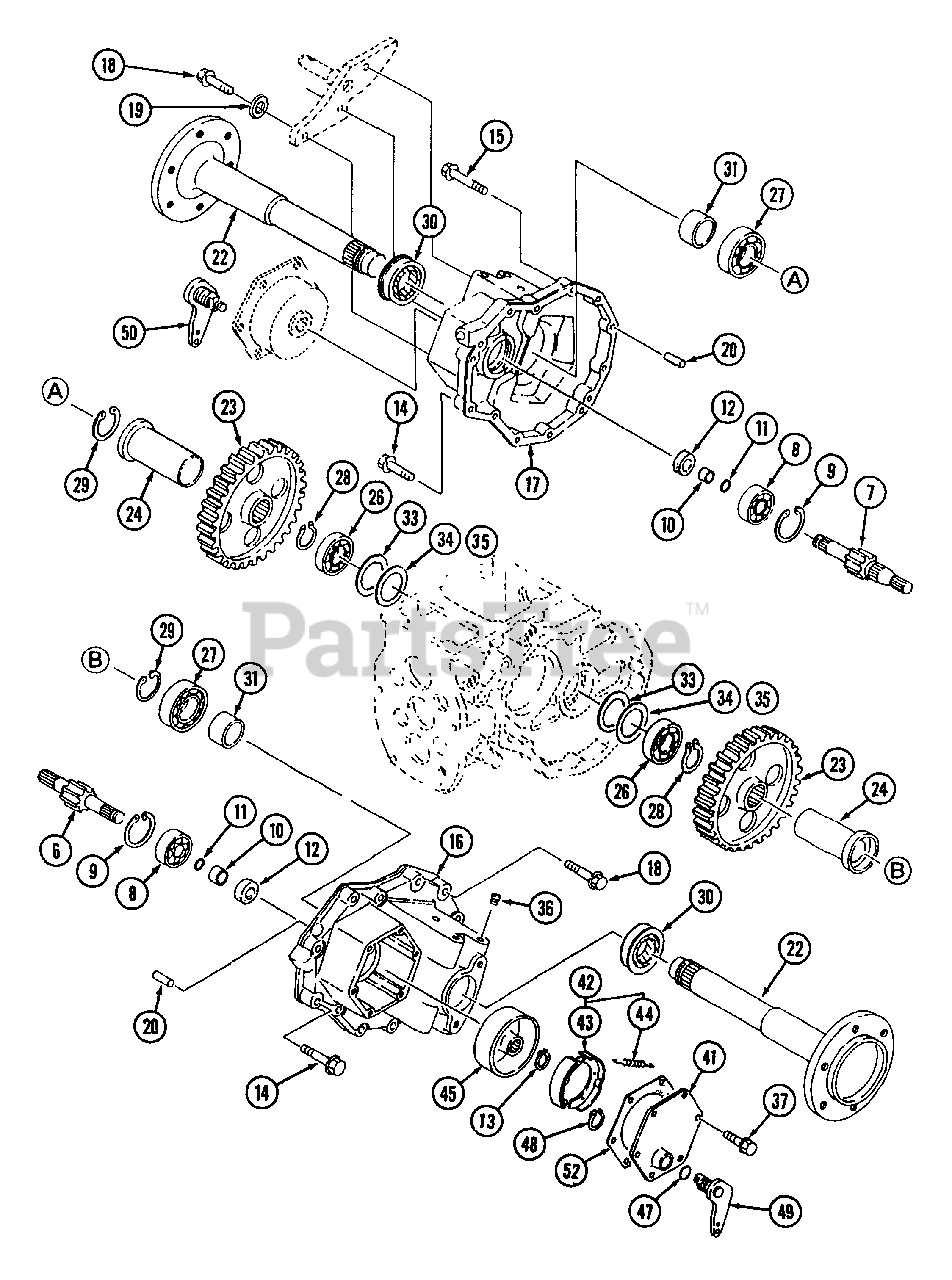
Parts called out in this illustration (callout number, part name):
14	Bolt
15	Bolt
43	Shoe, Brake
44	Spring
49	Cam Brake, L.H.
50	Cam Brake, R.H.
